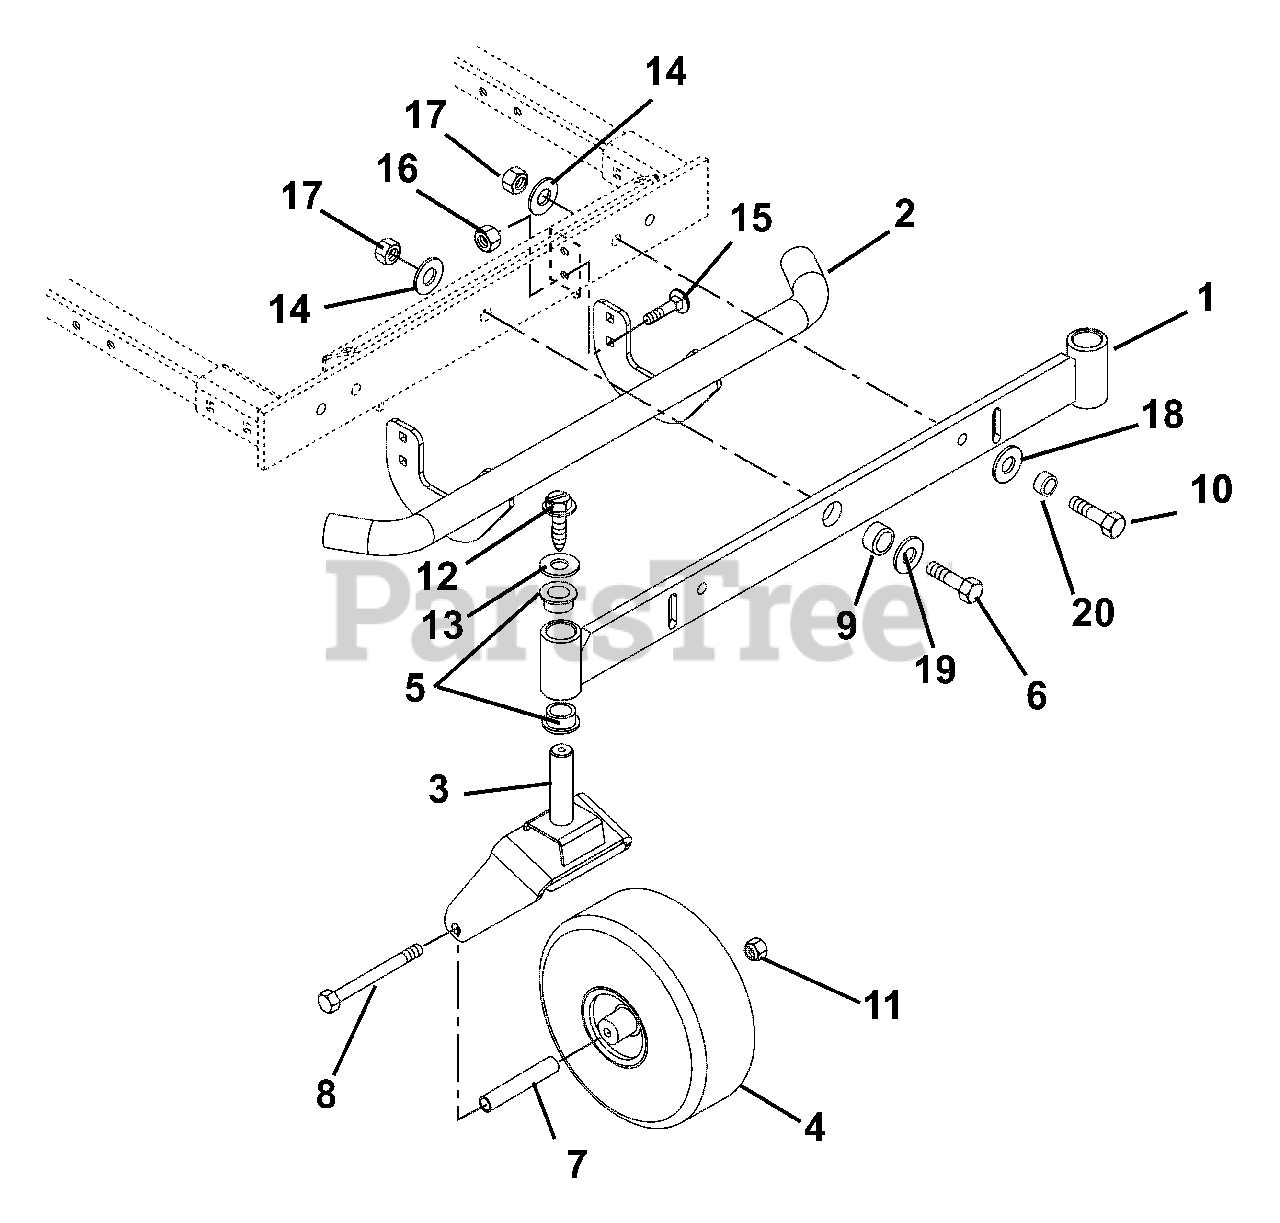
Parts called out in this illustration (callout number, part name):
1	WMT, FRONT AXLE
2	BUMPER-ZOOM
3	FORK,CASTER
4	ASSY-TIRE 4 X 11 - 4 PLY
5	BSHG-FLG 1.00X1.25X1.50X1.50EP
6	@BLT-HEX .62-11X2.50 GR5 YWZC
7	SPACER, ROLLED WHEEL
8	@BLT-HEX .50-13X6.50 GR5 YWZC
9	BUSHING, AXLE PIVOT
10	BLT-HEX .62-11X2.25 YWZC GR8
11	NUT-LK-TOP-FLG .50-13 YWZC
12	SCR-TAP .38-16X1.25 HWH TR BZC
13	WSHR-FL-STL .380X1.50X.125YWZC
14	WSHR-FLT .640X1.75X.250 YWZC
15	BLT-RDHDSQNK .38-16X1.00 G5YZ
16	@NUT-LK-NYL-FLG .38-16 YWZC
17	@NUT-LK-NYL .625-11 YWZC
18	@WSHR-FL-STL.812X1.50X.135YWZC
19	@WSHR-FL-STL.688X1.75X.134 YWZ
20	SPACER, .750 D X .558 LONG
